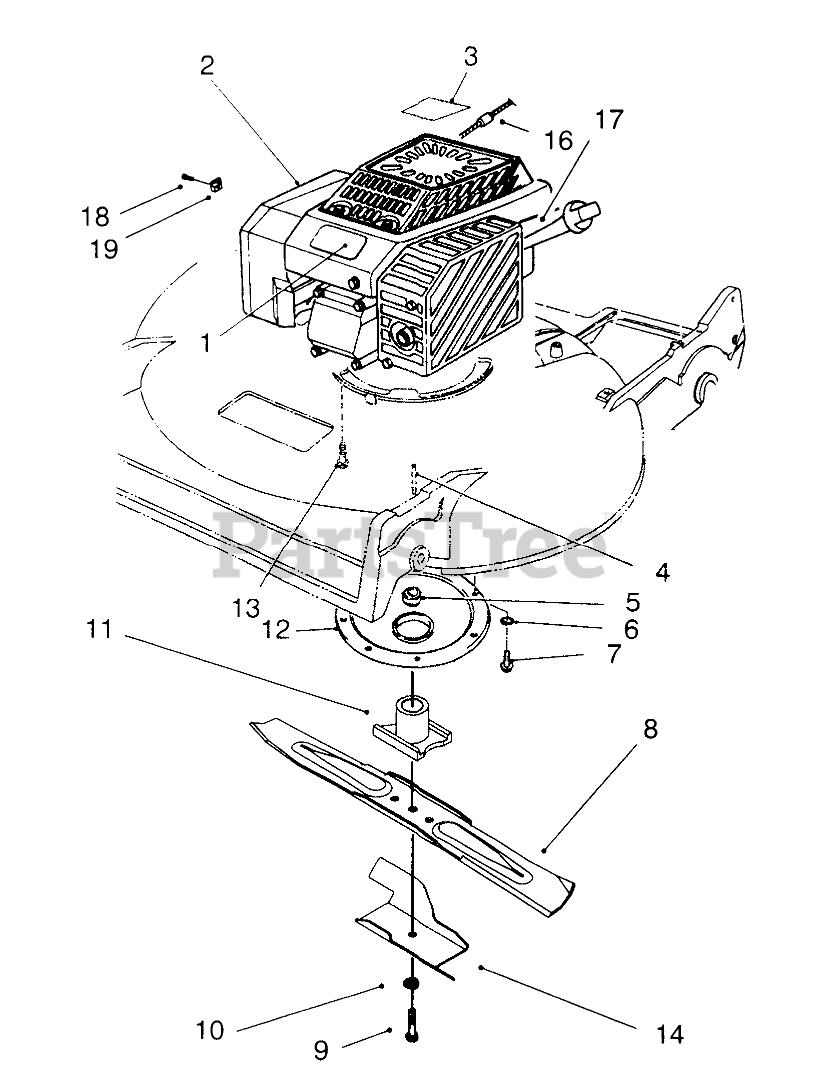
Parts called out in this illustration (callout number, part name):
1	DECAL - PROLINE
2	Engine-Complete
3	DECAL - ENGINE
4	KEY-SQUARE
5	SPACER-BLADE RETAINER
6	WASHER-LOCK, INTERNAL
7	SCREW-HWHTF
8	Blade
9	SCREW-BLADE
10	WASHER-LOCK
11	RETAINER-BLADE
12	PROTECTOR-CRANKSHAFT
13	SCREW-HWH
14	Accelerator
16	STOP-ROPE
17	COVER - BRAKE F/W
18	CLAMP SCREW F/W ENGINE
19	CLAMP-CASING
